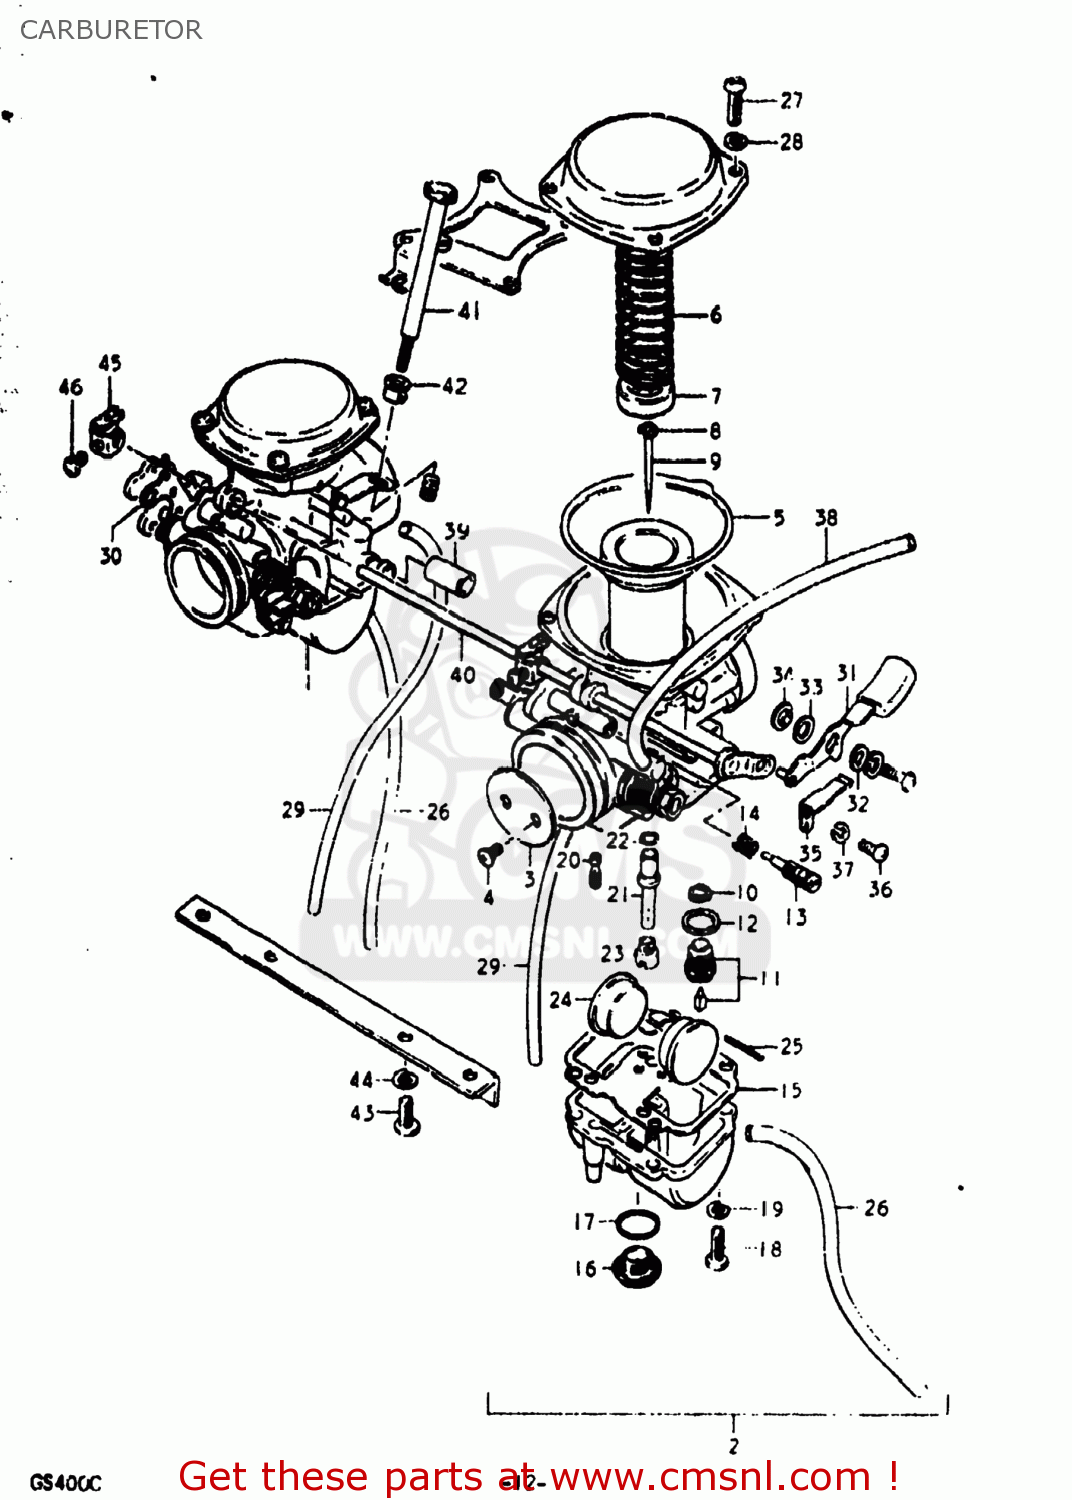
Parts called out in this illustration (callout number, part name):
0	CARBURETOR ASSEMBLY
1	CARBURETOR ASSEMBLY
2	CARBURETOR ASSEMBLY
3	VALVE,THROTTLE
4	SCREW
5	DIAPHRAGM ASSY
6	SPRING,DIAPHRAGM
7	CONNECTOR
8	CLIP
9	NEEDLE,JET
10	FILTER
11	VALVE ASSY,NEEDLE
12	GASKET,MAIN JET HOLDER (NAS)
13	SCREW,PILOT AIR
14	SPRING,THROTTLE SCREW
15	GASKET,FLOAT CHAMBER (NAS)
16	SCREW,GUIDE
17	O-RING
18	SCREW
19	LOCK WASHER
20	JET,PILOT
21	JET,NEEDLE
22	O-RING
23	SET, MAIN
24	FLOAT
25	PIN,FLOAT
26	HOSE
27	SCREW
28	LOCK WASHER
29	HOSE
30	GASKET
31	LEVER
32	WASHER,STARTER LEVER
33	WASHER,STARTER LEVER
34	RING,STARTER LEVER
35	SPRING
36	SCREW
37	LOCK WASHER
38	HOSE
39	HOSE
40	SHAFT,STARTER
41	ADJUSTER
42	BUSH
43	SCREW 6X12
44	LOCK WASHER
45	LEVER, STARTER
46	SCREW
